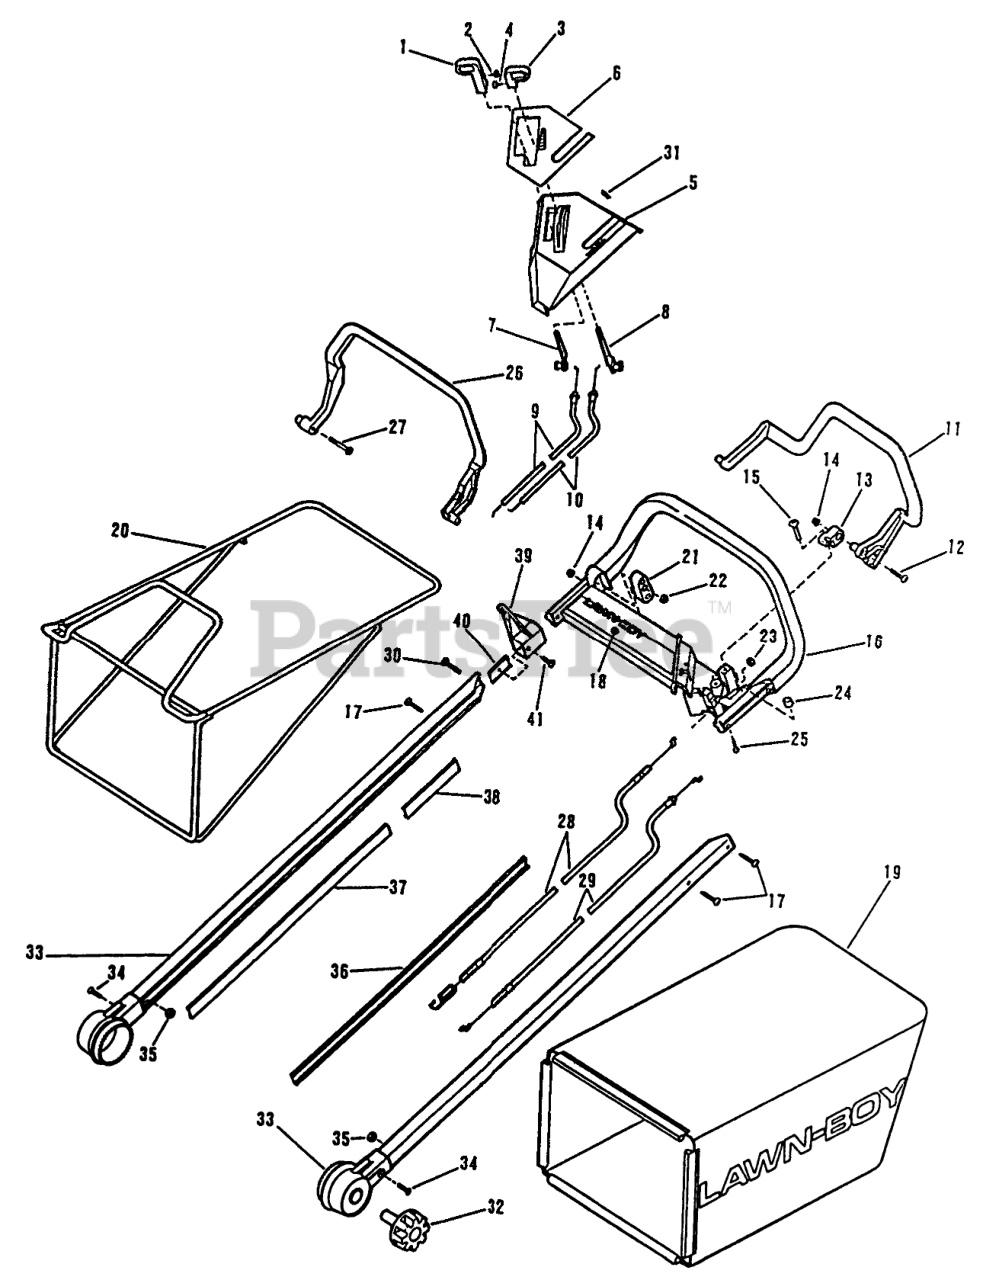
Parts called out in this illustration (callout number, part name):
1	KNOB & SCREW AY
2	SCREW-SELF TAP
3	KNOB & SCREW AY
4	SCREW-SELF TAP
5	UPPER CVR&DECAL AY
6	DECAL-LOGO-INSTR
7	LEVER ASSM SPD SEL LB
8	LVR ASSM THROTTLE LB
9	CABLE AY. WESCON
10	CABLE
11	BAIL-S.P.
12	SCREW - TRUSS HEAD
13	PIVOT BAIL PL
14	LOCKNUT FLAN
15	SCREW - TRUSS HEAD
16	HANDLE & DECAL AY.
17	TENSIONER BRKT
18	DECAL - LAWNBOY
19	REPL BAG FOR 684190
20	FRAME AY-GRASS BAGB
21	BLOCK BAIL PL
22	LOCKNUT E
23	NUT - HEX JAM
24	BUMPER
25	SCREW - TRUSS HEAD
26	Blade Brake Bail
27	SCREW - TRUSS HEAD
28	Cable Assy-Self-propelled
29	CABLE ASSEMBLY
30	SCREW-TRUSS
31	PLUG - BUTTON
32	KNOB-HDLE MT.ASMB
33	Handle Shaft Assembly
34	SCREW
35	LOCKNUT FLAN
36	Handle Insert-Cable Side
37	INSERT-HANDLE
38	INSERT - HANDLE
39	ROPE GUIDE AY
40	NUT LB
41	SCREW
